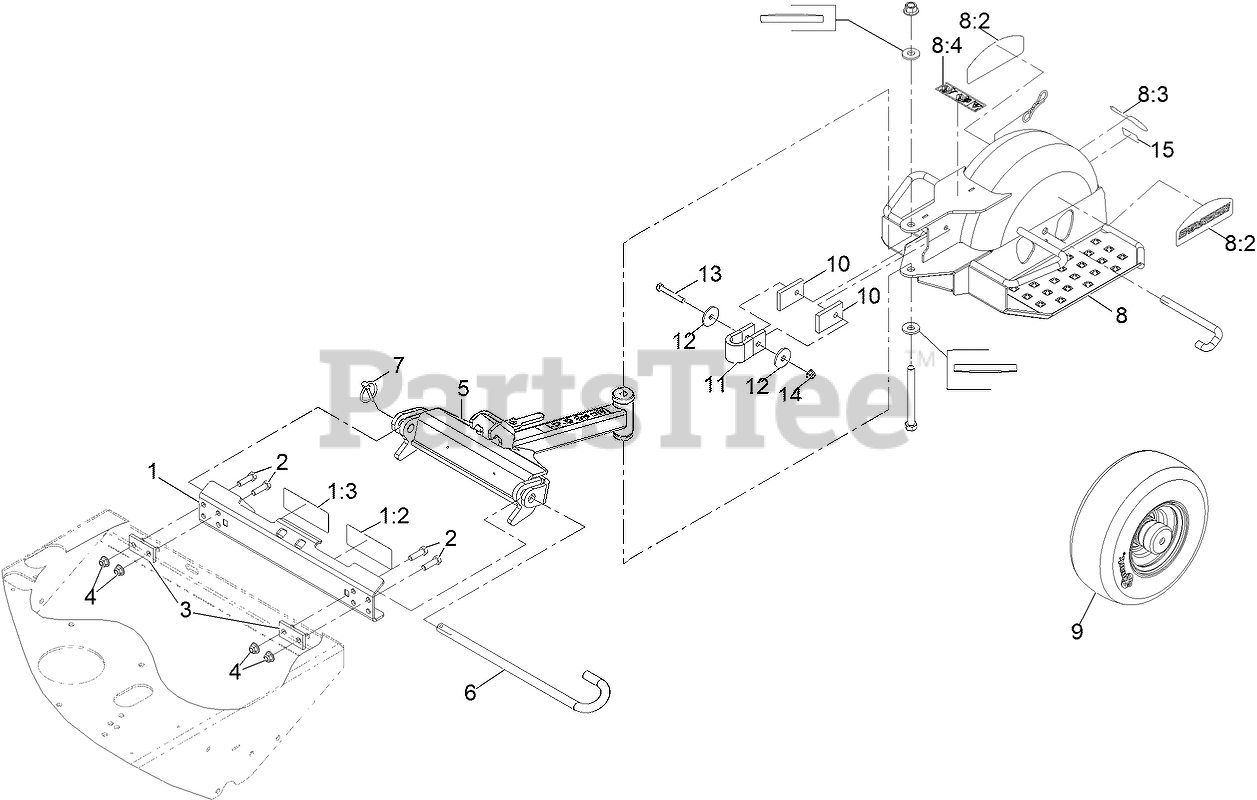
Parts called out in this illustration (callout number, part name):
1	ASM, MOUNT PLATE
1:2	DECAL-BELT DRIVE WARNING
1:3	DECAL-WARNING, SULKY
2	SCREW-HH
3	PLATE,BACK-UP (PLATED)
4	NUT-HF, NI
5	ASM, DRAW BAR
6	PIN, PIVOT
7	PIN-LYNCH
8	ASM-SULKY FRAME W/ DECALS
8:2	DECAL, STANDON
8:3	DECAL, EXMARK
8:4	DECAL-WARNING HAND PINCH
9	ASM, WHEEL AND BEARINGS
10	PAD,STOP
11	STOP, ROTATION
13	SCREW-HH
14	NUT-HF, NI
15	Decal-Patent Ttco.Com
